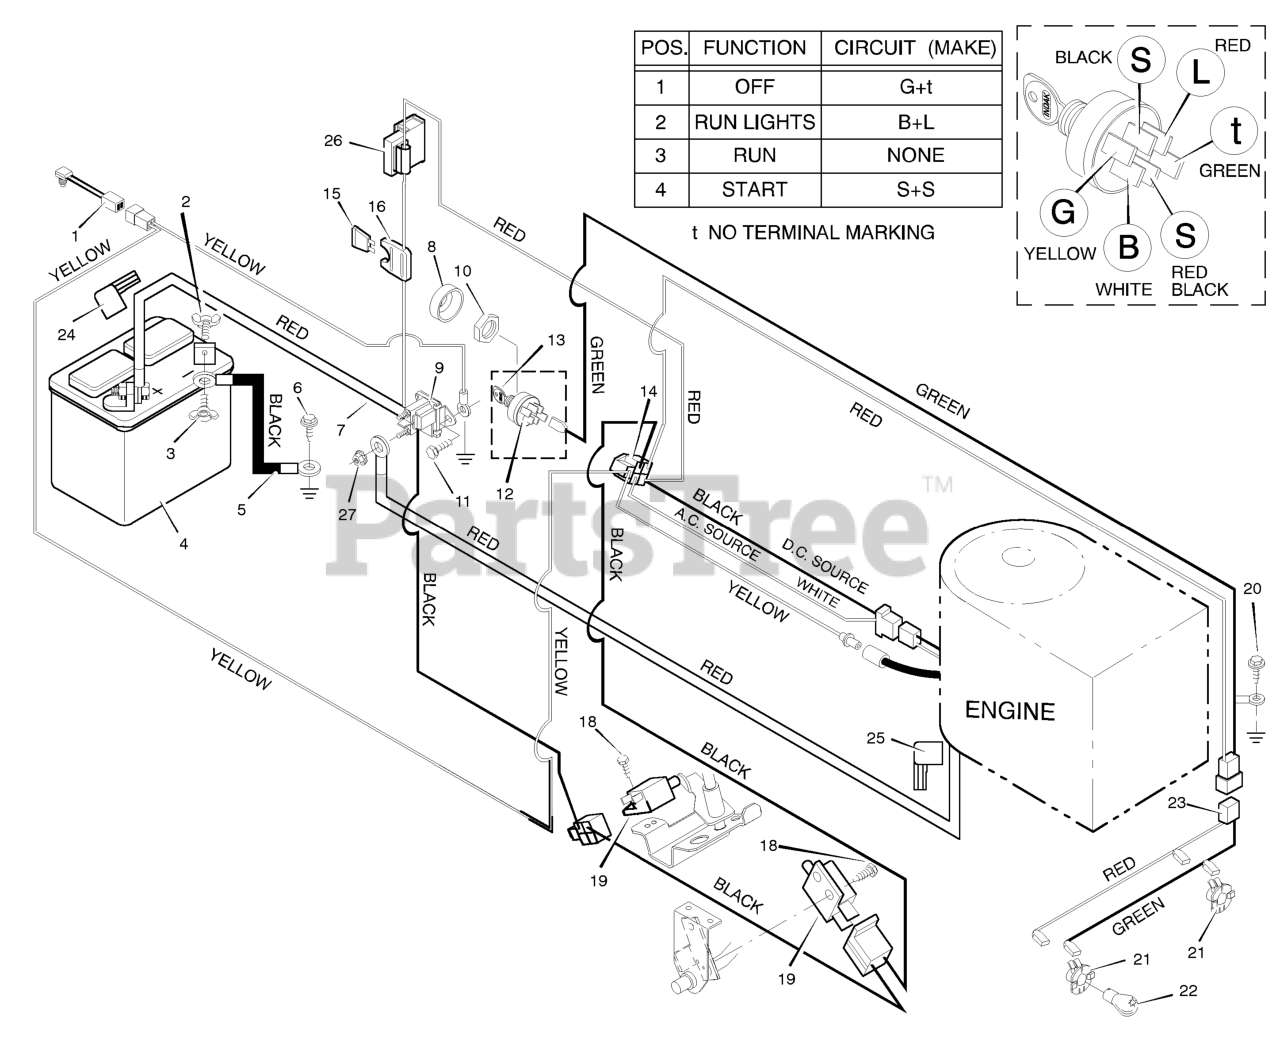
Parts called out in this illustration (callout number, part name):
1	Switch, Seat Sensor
2	Locknut
3	Bolt, Hex
3	Wingnut
4	Battery
5	Cable, Battery Ground
7	Cable, Red Battery
8	Cap, Ignition
9	Solenoid
10	Nut
12	Switch, Ignition
13	Key, Ignition
14	Harness, Chassis Wire
16	Holder, Fuse
19	Switch, Clutch
20	Screw
21	Socket, Light
22	Bulb, Light
23	Harness, Light Wire
24	Cover, Terminal
25	Cover,
26	Ammeter
27	Locknut
